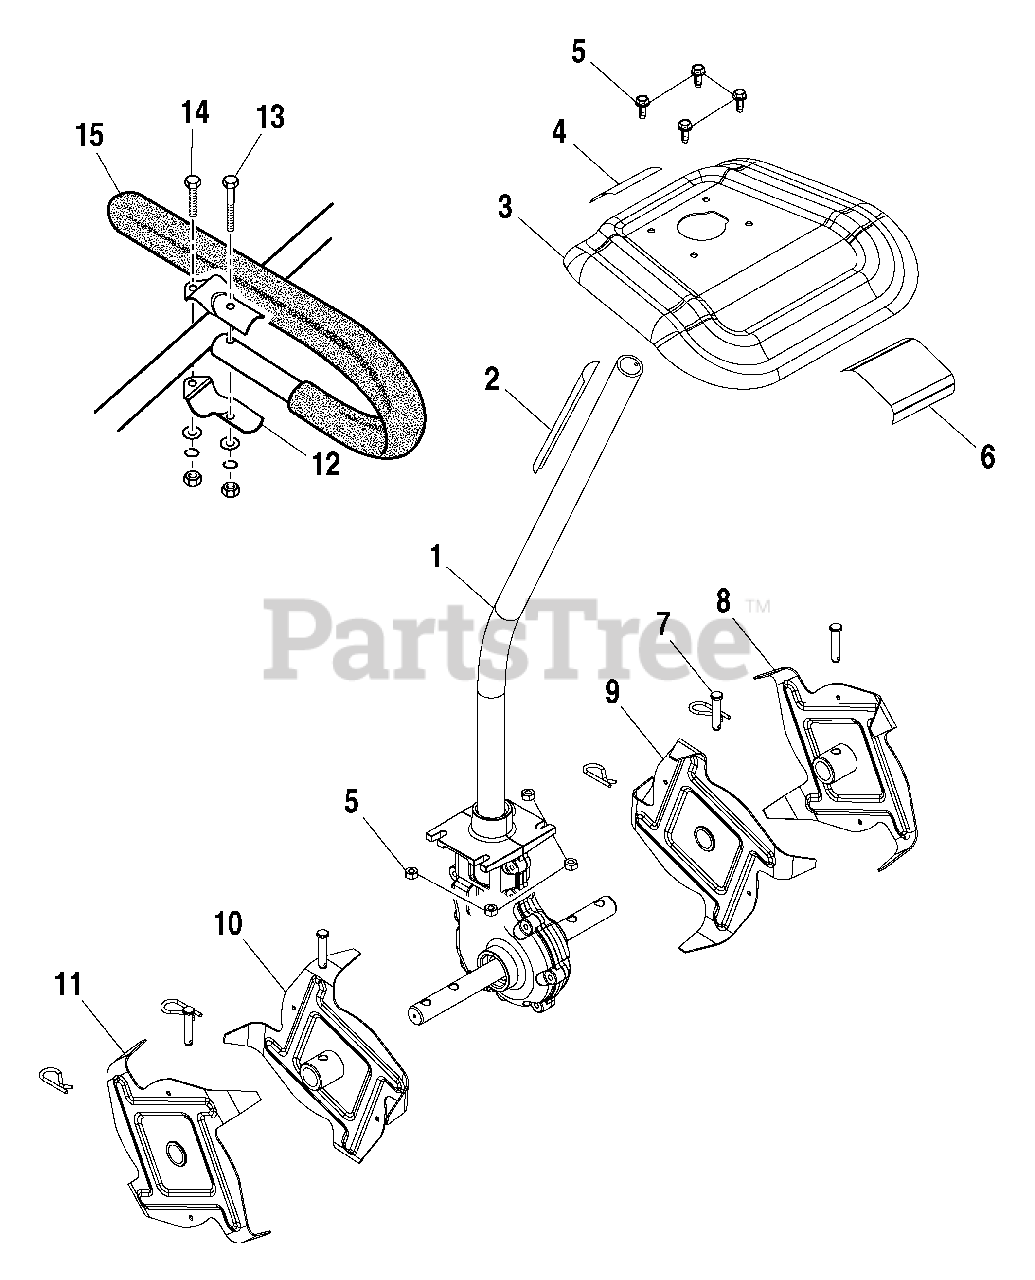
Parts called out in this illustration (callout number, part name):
1	GEAR CASE AND BOOM ASSEMBLY
2	WARNING LOGO
3	TILLER SHIELD
4	EXPAND-IT TILLER DECAL
5	SCREW AND LOCK NUT
6	WARNING LOGO
7	CLEVIS AND HINGE PIN
8	TINE D ASSEMBLY
9	TINE C ASSEMBLY
10	TINE B ASSEMBLY
11	TINE A ASSEMBLY
12	HANDLE BAR CLAMP
13	BOLT ASSEMBLY (M6 X 40)
14	BOLT ASSEMBLY (M6 X 25)
15	J HANDLE AND GRIP
